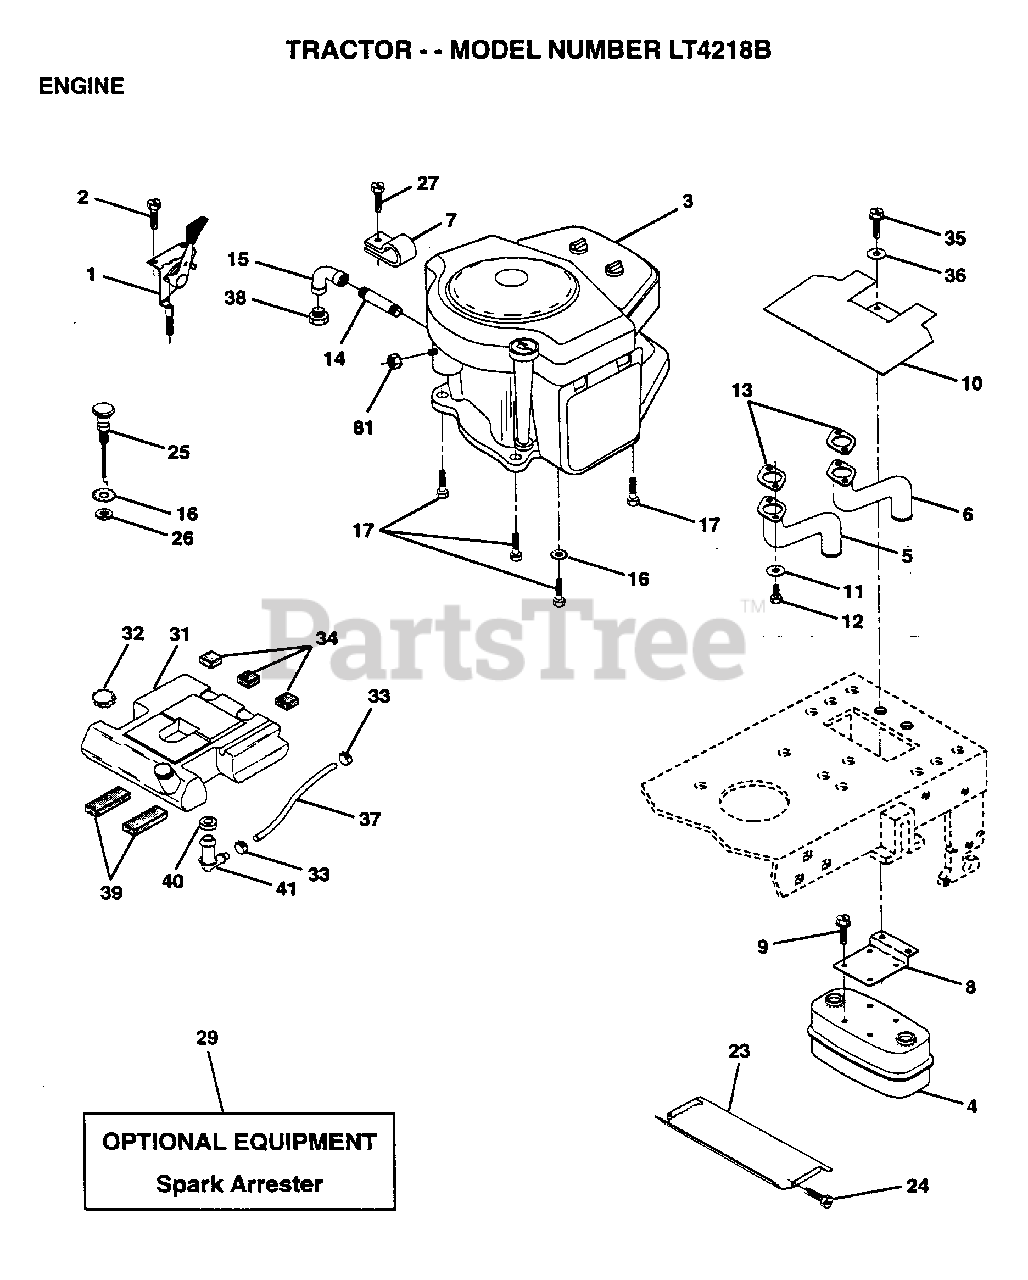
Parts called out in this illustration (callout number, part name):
1	CONTROL.THT.FLG.
2	SCREW LT
3	ENGINE B&S 18HP
7	CLAMP.TUBE.DBL.EN
11	LOCKWASHER
14	PIPE NIPPLE LT
15	ELBOW
16	LOCKWASHER
17	SCREW LT
25	CHOKE CONTROL
27	SCREW.10-24X1/2
28	NUT
31	TANK FUEL 1.9 NAT
32	CAP ASM FUEL
33	HOSE CLAMP
37	LINE FUEL
39	"STRIP,FORM"
42	STRAP TANK FUEL
43	STRAP TANK FRONT
44	SCREW
47	EXHAUST TUBE T
48	MUFFLER GUARD
49	SCREW
50	WASHER HYT
51	BOLT D
52	NUT
